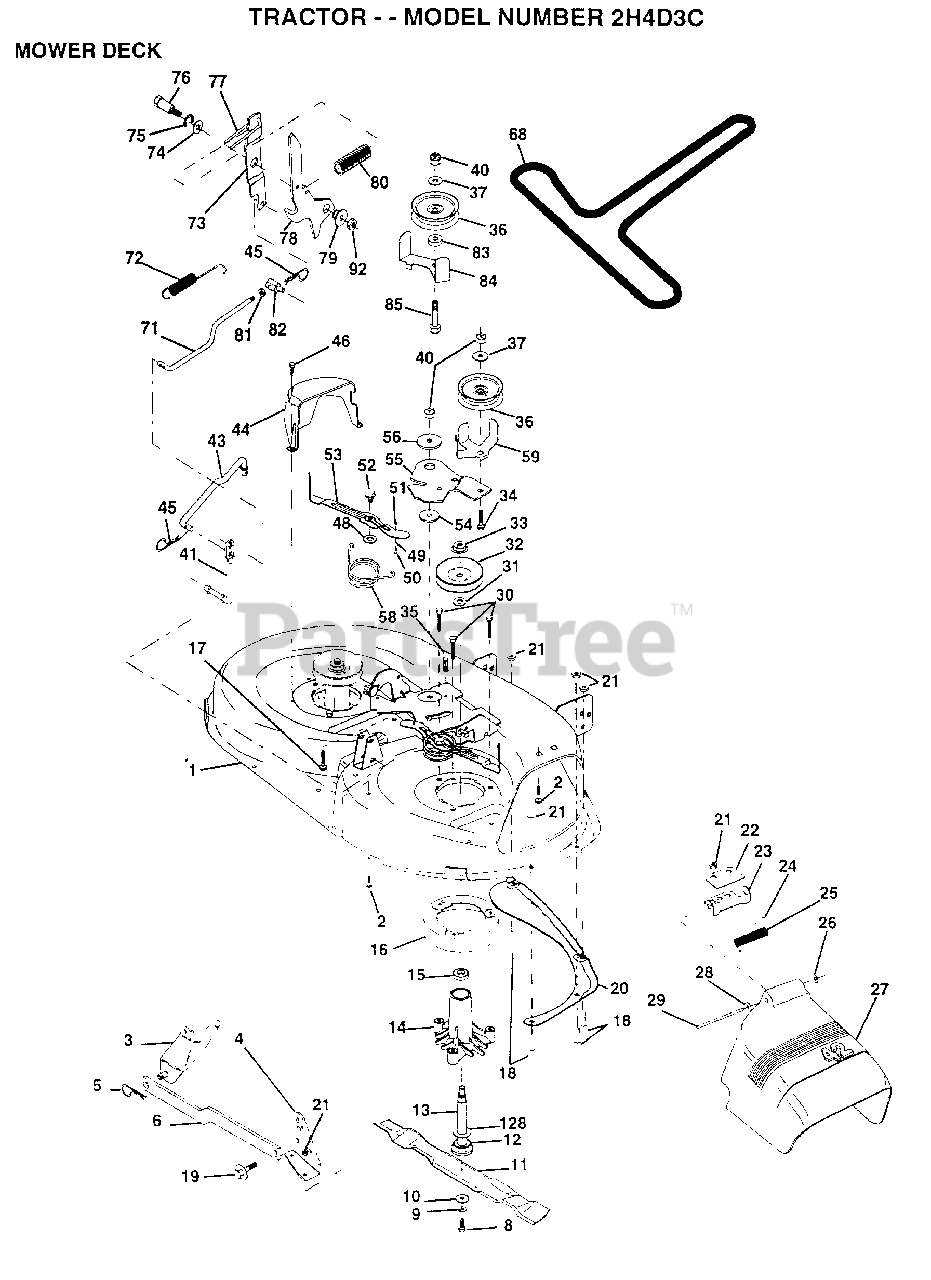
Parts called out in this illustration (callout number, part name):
1	DECK.WELD.42.
2	BOLT
3	BRKT ASM SWAY BAR
4	BRKT DECK SW BAR
8	BLADE BOLT
10	WASHER.HARD.BLADE
11	"BLADE.42"" HIPERF"
12	BEARING.BALL
14	HSG ASM MANDREL
15	BEARING
16	STRIPPER RND MWR
17	BOLT RDHD 3/8-16
18	BOLT
19	BOLT SHD 5/16-18
22	STIFFENER BRKT
23	DEFLECTOR BRKT
24	CAP-SLEEVE LT
25	SPRING TORSION
26	NUT PUSH M
27	DEFLECTOR.SHIELD
28	WASHER
29	HINGE ROD
31	WASHER
32	PULLEY.MANDREL.42
34	BOLT
35	XMAS TREE FASTNER
36	FLAT IDLER PULLEY
37	WASHER
41	PIVOT ROD
43	ROD CLUTCH W/NIBS
44	GUARD MAND LH BLK
45	RETAINER M
46	SCREW.1/4-20X5/8
48	HARD SMALL WASHER
50	SHOULDER BOLT
51	LOCKNUT
52	BOLT.SHLD.5/16-18
53	BRAKE PAD ARM ASM
54	HARDENED WASHER
56	SPACER RETAINER
58	SPRING TORSN BRAK
59	GUARD IDLER TUV
68	BELT.V.T-PATH
71	ROD CLUTCH 38/42
72	SPRING.EXT.RETURN
73	CLUTCH ARM SECOND
74	WASHER
75	RING
76	SHOULDER BOLT
77	SPRING KEEPER
79	BUSHING
80	SPRING.CLUTCH.MWR
81	NUT
82	TRUNION ADJ
83	WASHER
85	BOLT RDHD 3/8-16
92	NUT
128	WASHER.FELT.
